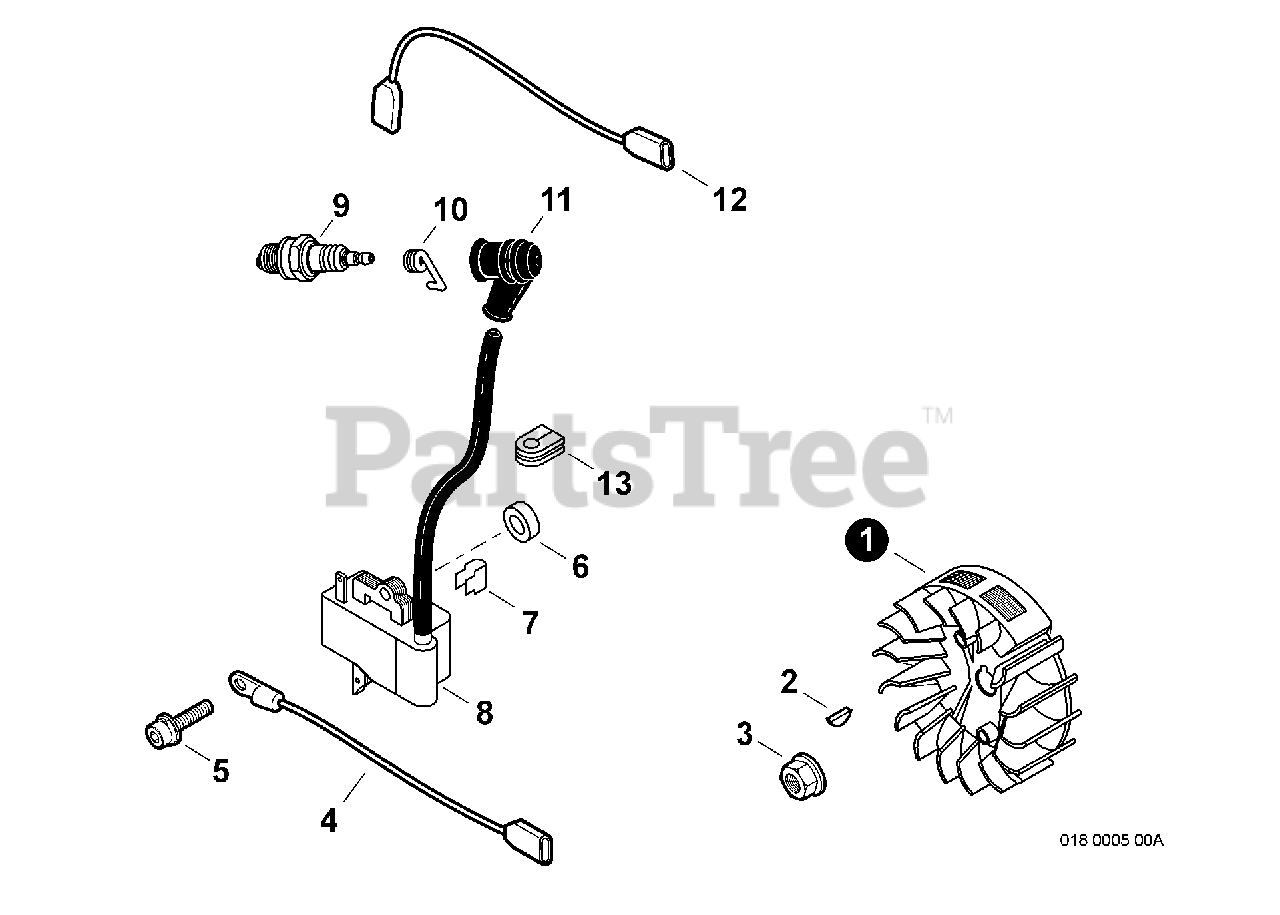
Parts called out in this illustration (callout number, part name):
1	FLYWHEEL
2	KEY, WOODRUFF
3	NUT, FLANGE M8
4	LEAD - GROUND L= 140
5	BOLT 5×20
6	WASHER 5.2×12×3
8	COIL, IGNITION
9	SPARK PLUG - BPMR8Y
10	TERMINAL, SPARK PLUG
11	CAP, SPARK PLUG
12	LEAD - IGNITION L= 172
13	GROMMET
